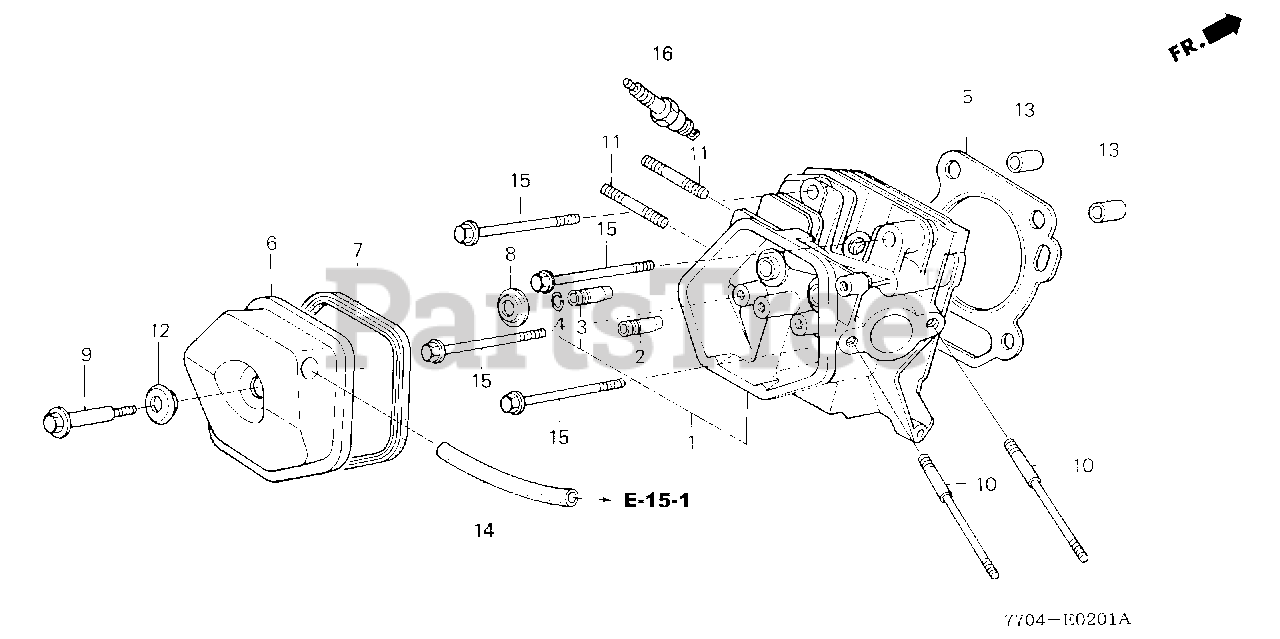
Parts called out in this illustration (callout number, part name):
1	CYLINDER HEAD
2	GUIDE, VALVE (OVER SIZE)
3	GUIDE, EX. VALVE (OVER SIZE)
4	CLIP, VALVE GUIDE
5	GASKET, CYLINDER HEAD
6	COVER, HEAD
7	GASKET, HEAD COVER
8	SEAT, VALVE SPRING
9	BOLT, HEAD COVER
10	BOLT, STUD (8X123)
11	BOLT, STUD (8X32)
12	WASHER, HEAD COVER
13	PIN, DOWEL (12X20)
14	BULK HOSE, VACUUM (11X1000) (11X100)
15	BOLT, FLANGE (10X80)
16	SPARK PLUG (BPR5ES) (NGK)
16	SPARK PLUG (W16EPR-U) (DENSO)
